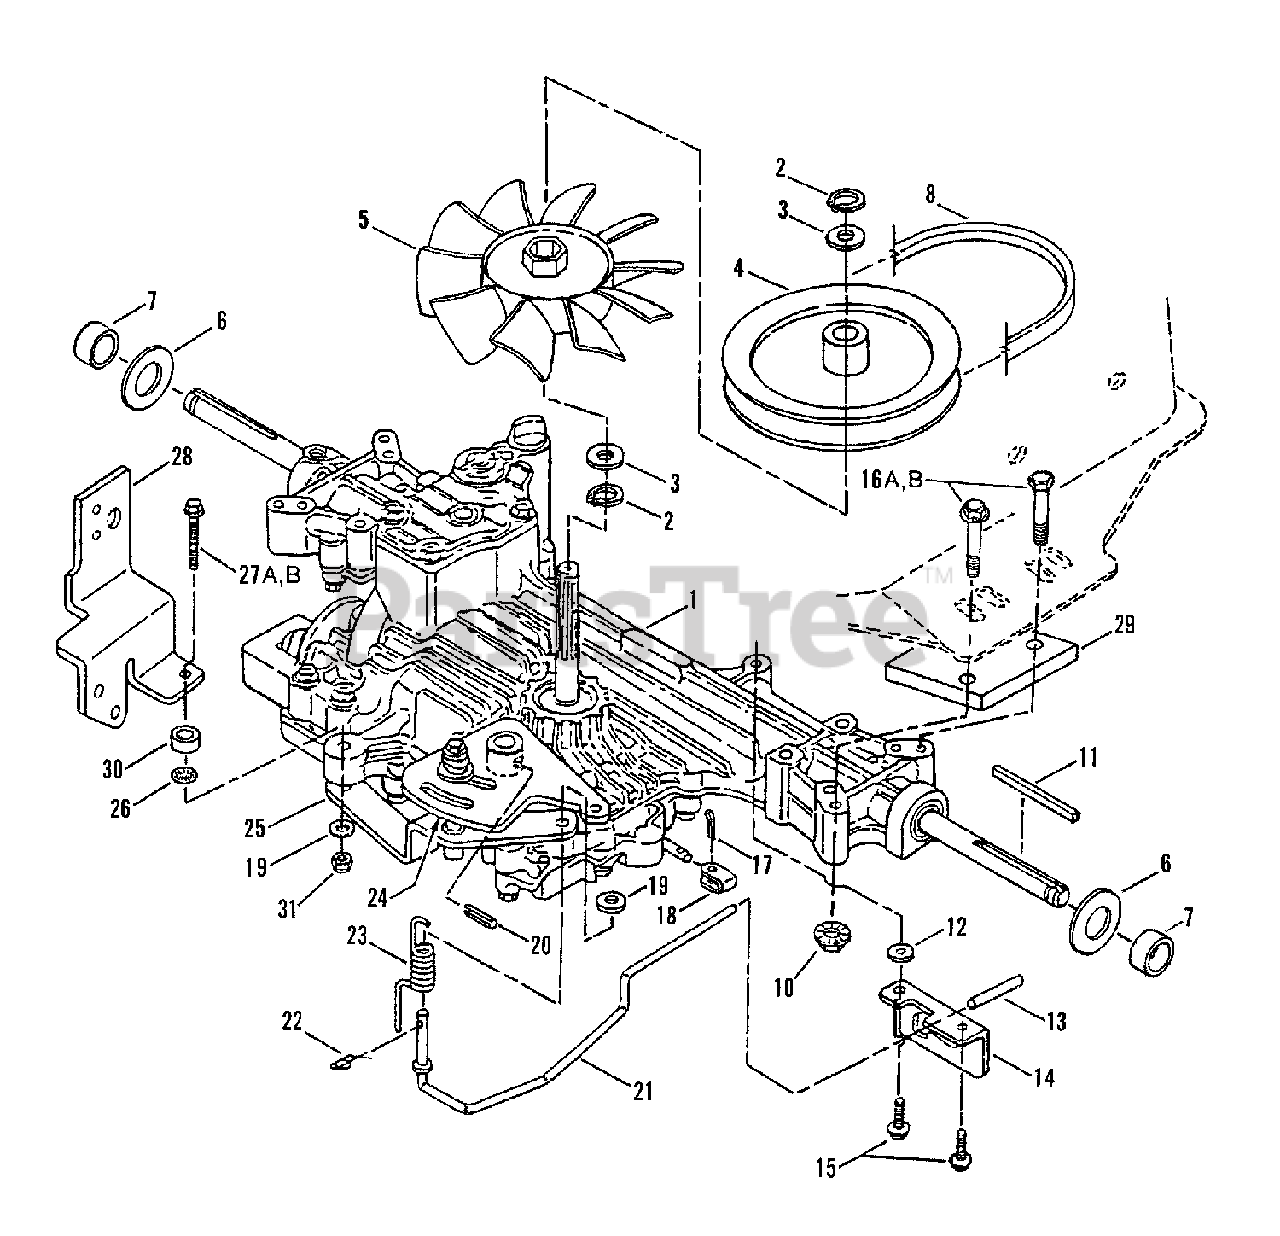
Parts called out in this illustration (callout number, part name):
1	TRANSAXLE, Hydro Drive, Tuff-Torq Model K50
1	TRANSAXLE, Hydro Drive, Tuff-Torq Model K55
2	RING, External Retaining 13.8 mm
3	WASHER, Fan/Hub
4	PULLEY, Drive
5	FAN
6	WASHER, Flat, 1/8 x 25/32" I.D. x 1-1/2" O.D.
8	BELT, Traction Drive
8	BELT, TTK50/K55 Traction Drive- 20" HA96
10	NUT, 5/16-18 Hex Flange Lock Grade 5
11	KEY, Square, 3/16 x 3/16 x 2-1/2"
12	WASHER, Flat, 3/4" O.D.
13	GRIP, Roll Release
14	DETENT, Roll Release
15	SCREW, 3/8-16 x 1-3/4" Self-Tapping
16A	BOLT, 5/16-18 x 2-1/4" Hex. Flange. Lock, Gr. 2
16B	SCREW, 5/16-18 x 2-3/4, Gr. 5
17	COTTER-PIN, 5/32 x 1"
18	LINK, Roll Release
19	WASHER, 11/32 x 11/16 x 1/16"
20	ROLL-PIN, 6 mm x 32 mm
21	WIRE FORM, Roll Release
22	COTTER-PIN, 5/16 Self-Locking
23	SPRING, Torsion (Roll Release)
24	ASSEMBLY, Speed Control/Friction
25	SUPPORT, Friction Stud Assembly
26	RETAINER, 5/16 Bolt
27A	BOLT, 5/16-18 x 2" Hx. Flg. Lk., Grade 5
27B	BOLT, 5/16-18 x 2-1/4" Hex. Flange. Lock, Grade 2
28	BRACKET, Spool
29	SPACER, Axle
30	SPACER, Torque, 3/8" Thick
31	NUT, 5/16-18 Hex Lock
